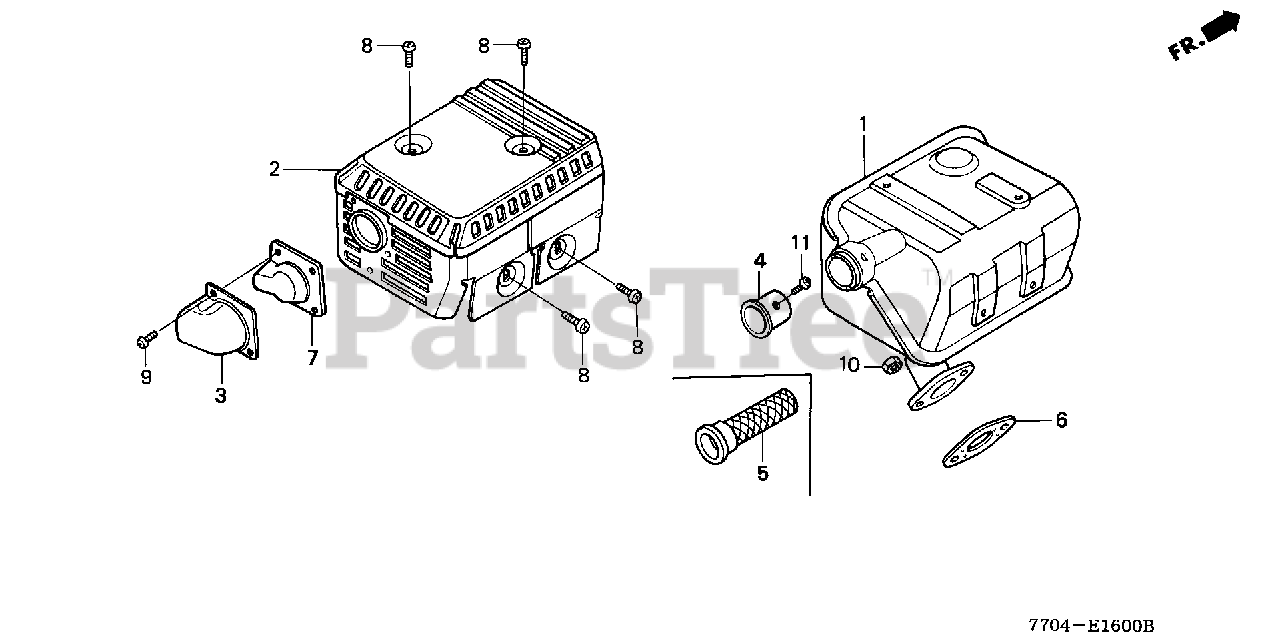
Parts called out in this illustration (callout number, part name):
1	MUFFLER (STD)
1	MUFFLER (ARRESTER)
2	PROTECTOR, MUFFLER (STD) (BLACK)
3	DEFLECTOR, MUFFLER
4	PIPE, TAIL
5	ARRESTER, SPARK
6	GASKET, MUFFLER
7	GUIDE, MUFFLER
8	SCREW, TAPPING (5X8)
9	SCREW, TAPPING (4X6)
10	NUT, HEX. (8MM)
11	SCREW, TAPPING (4X6)
